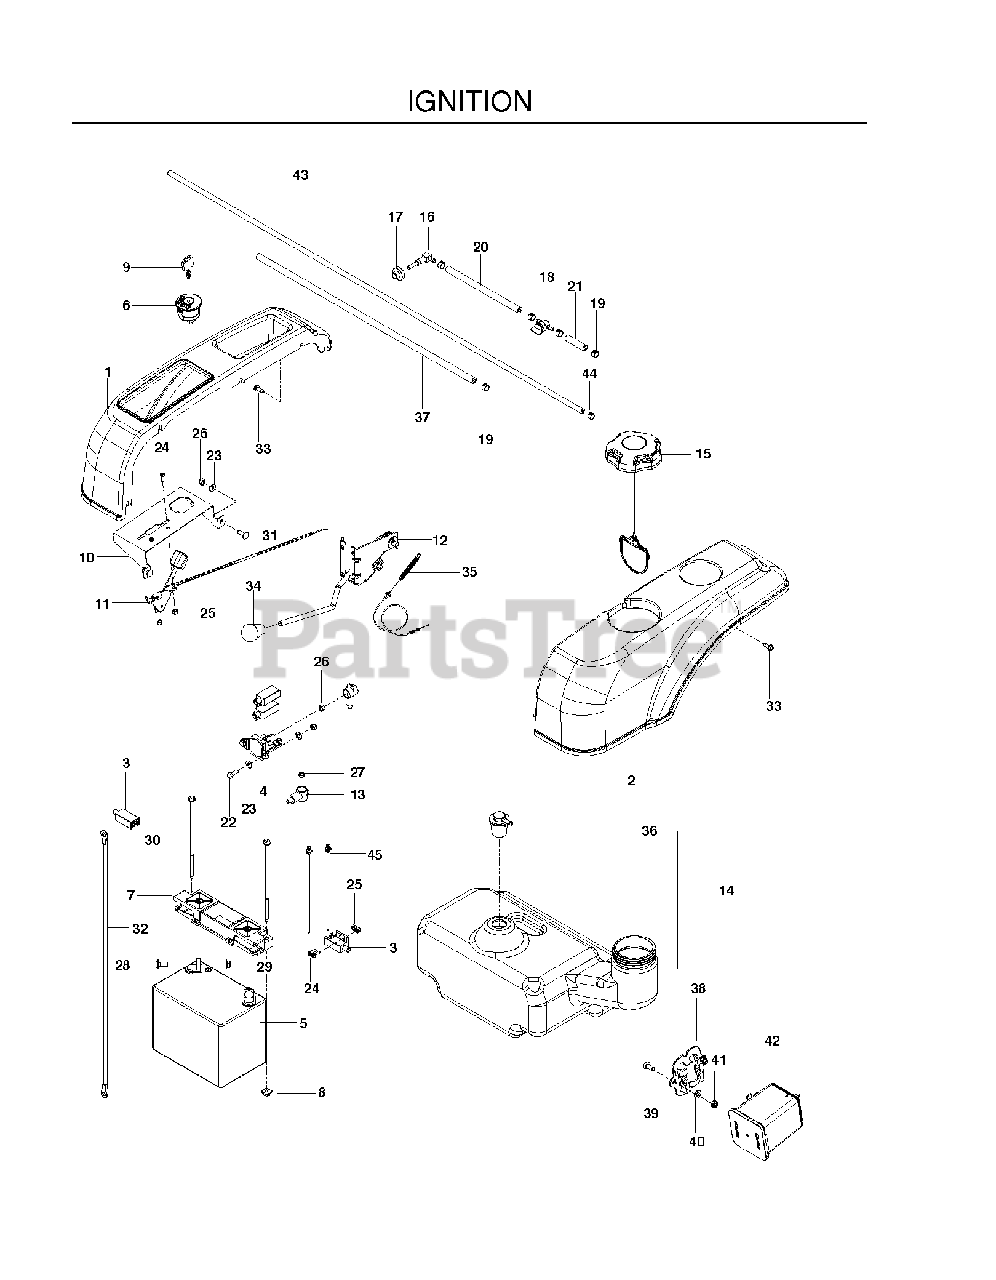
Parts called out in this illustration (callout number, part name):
1	FENDER, RZ 30/38 RT
2	FENDER, RZ 30/38 LT
3	SWITCH, INTERLOCK
4	SOLENOID
5	BATTERY, 12 V 330 AMP TBR
6	IGNITION SWITCH
7	BATTERY HOLD DOWN
8	PUSH NUT-NYLON
9	KEY
10	MOUNT, CONTROLS, BLK
11	THROTTLE CABLE
12	ASM, CLUTCH ENGAGE W/CABLE
13	TERMINAL COVER-SM
15	CAP, FUEL
16	ELBOW W/FILTER
17	TANK FITTING
18	FUEL VALVE
19	HOSE CLAMP
20	HOSE 1/4 X 8
21	HOSE 1/4 X 2"
22	HCS 1/4C X 3/4 HCS
23	WASHER 1/4 SAE
24	SCREW #10-24 X 5/8
25	NUT 10-24 NYLOC
26	NUT 1/4-20 NYLOC
27	JAM NUT 1/4C
28	BOLT 5/16C X 3/4" CARRIAGE
29	5/16-18 NYLOC FLANGE NUT
30	BOLT - 1/4-20 X 7.5
31	RHSNB 1/4C X 3/4
32	BATTERY CABLE, NEGATIVE
33	SCREW 1/4 X 5/8
34	KNOB - SHIFT
35	CABLE.CLUTCH.38".SERVICE
37	FUEL LINE 24"
38	BRACKET, CANISTER
39	HCS 5/16-18 X 5/8 GR 5 ZD
40	FLAT WASHER 5/16 SAE
41	5/16-18 THIN PROF NY
42	CANNISTER, CARBON
43	HOSE, FUEL 3/16" X 42"
44	CLAMP, HOSE
45	TIE, PLASTIC
